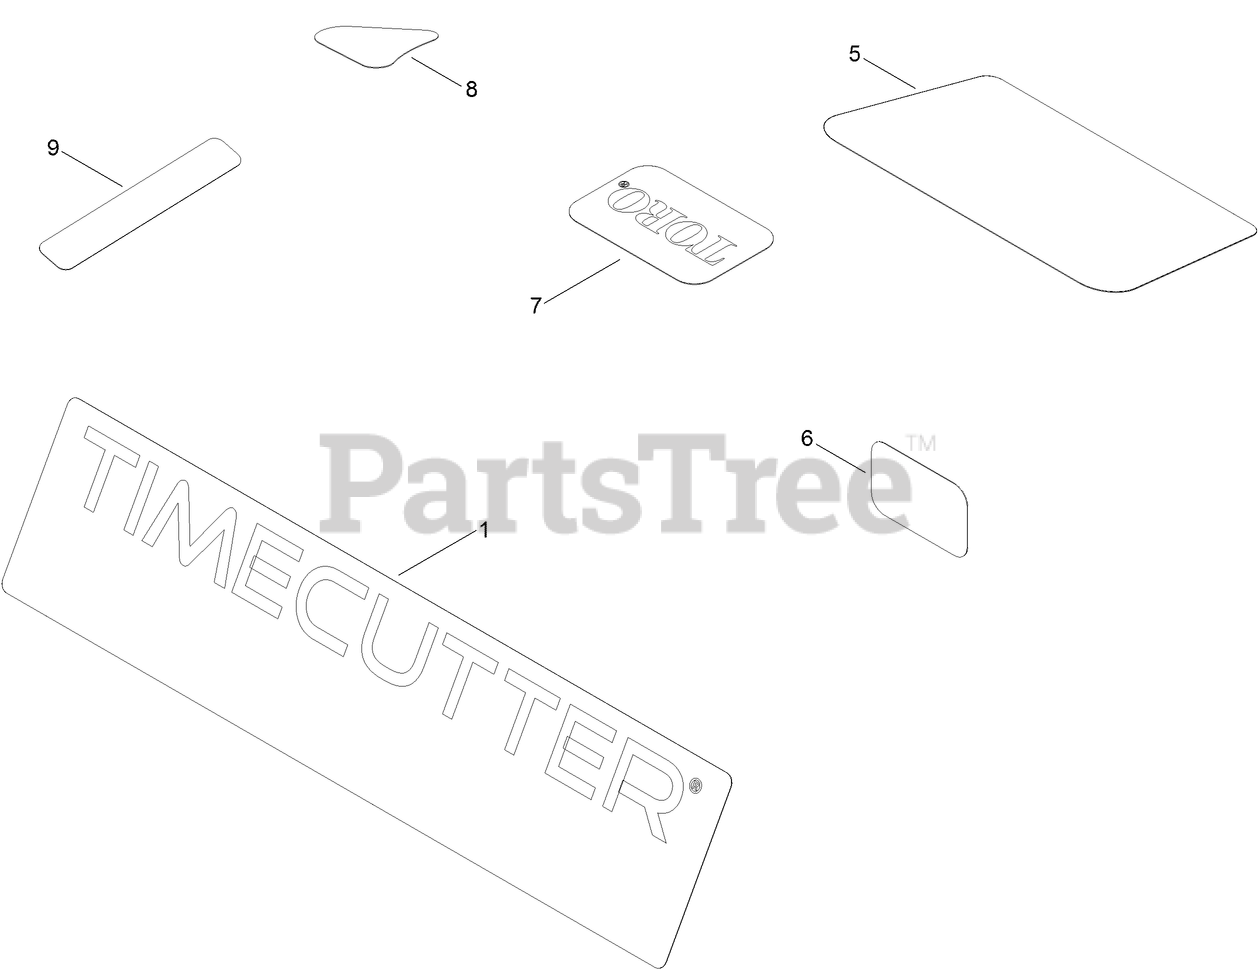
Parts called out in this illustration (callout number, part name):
1	DECAL-TIMECUTTER
5	DECAL-ENGINE
6	PLACARD-INTAKE
8	DECAL-DRAIN, OIL
9	DECAL-SHUTDOWN
